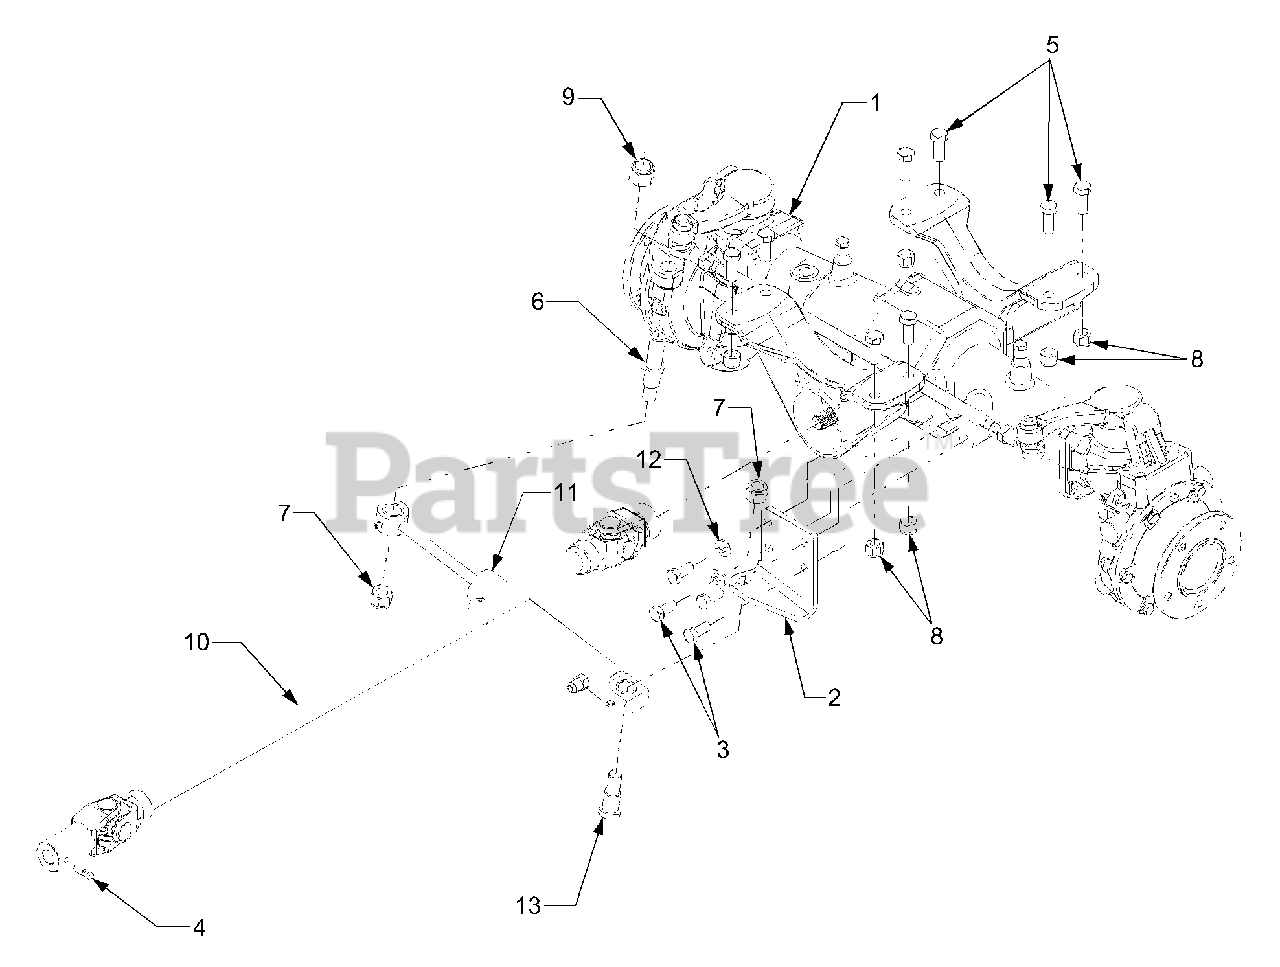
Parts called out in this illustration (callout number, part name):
1	Axle, 4WD Front
4	Screw, Sq. Hd Lock. 5/16-18
5	Screw, Hex Cap 1/2-13 x 1.5 GR5
6	Stud, Cylinder Mounting
7	Nut, Hex Insert Lock 5/8-11 GR5
8	Nut, Hex Insert Lock, 1/2-13 GR8
9	Nut, Hex Lock, 3/4-10 GRC
10	Shaft, 4WD Drive
11	Cylinder, Steering
12	Washer, Lock, 1/2
13	Screw, Shoulder, .75 x 1.03
